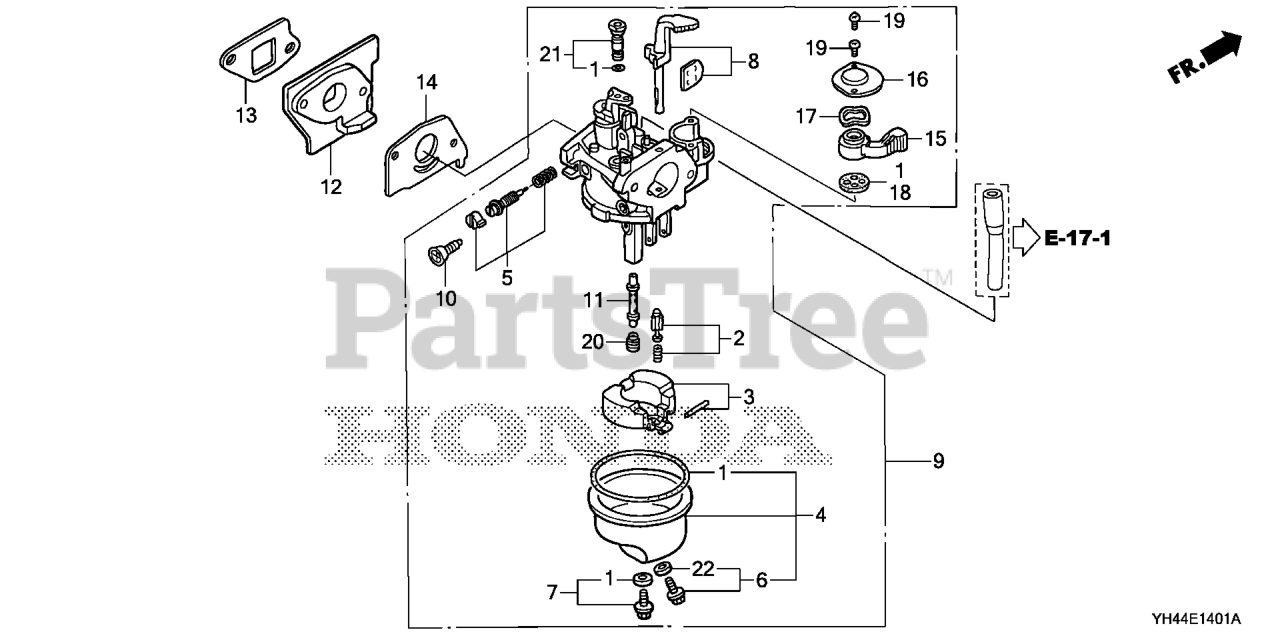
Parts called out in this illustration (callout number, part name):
1	GASKET SET
2	VALVE SET, FLOAT (CARBURETOR NO.) (SEAT NOT INCLUDED)
4	CHAMBER SET, FLOAT (CARBURETOR NO.)
5	SCREW SET
6	SCREW SET, DRAIN (Honda Code 1672187). (CARBURETOR NO.)
7	SCREW SET (CARBURETOR NO.)
8	CHOKE SET (CARBURETOR NO.)
9	CARBURETOR ASSY. (BF32P A)
10	SCREW, THROTTLE STOP
11	NOZZLE, MAIN
12	INSULATOR, CARBURETOR
13	GASKET, INSULATOR (ENGINE NO.)
14	GASKET, CARBURETOR
15	LEVER, VALVE (CARBURETOR NO.)
16	PLATE, LEVER SETTING (CARBURETOR NO.)
17	SPRING, PETCOCK LEVER (CARBURETOR NO.)
18	GASKET, VALVE
19	SCREW, PAN (3X6)
20	JET, MAIN (#50) Use from Engine SN BF12A B.
20	JET, MAIN (#52) Use from Engine SN BF12A B.
20	JET, MAIN (#55) Use from Engine SN BF22B D.
21	JET SET, PILOT (#38)
22	WASHER, PLAIN (6.2X10.7 DRAIN) (CARBURETOR NO.)
